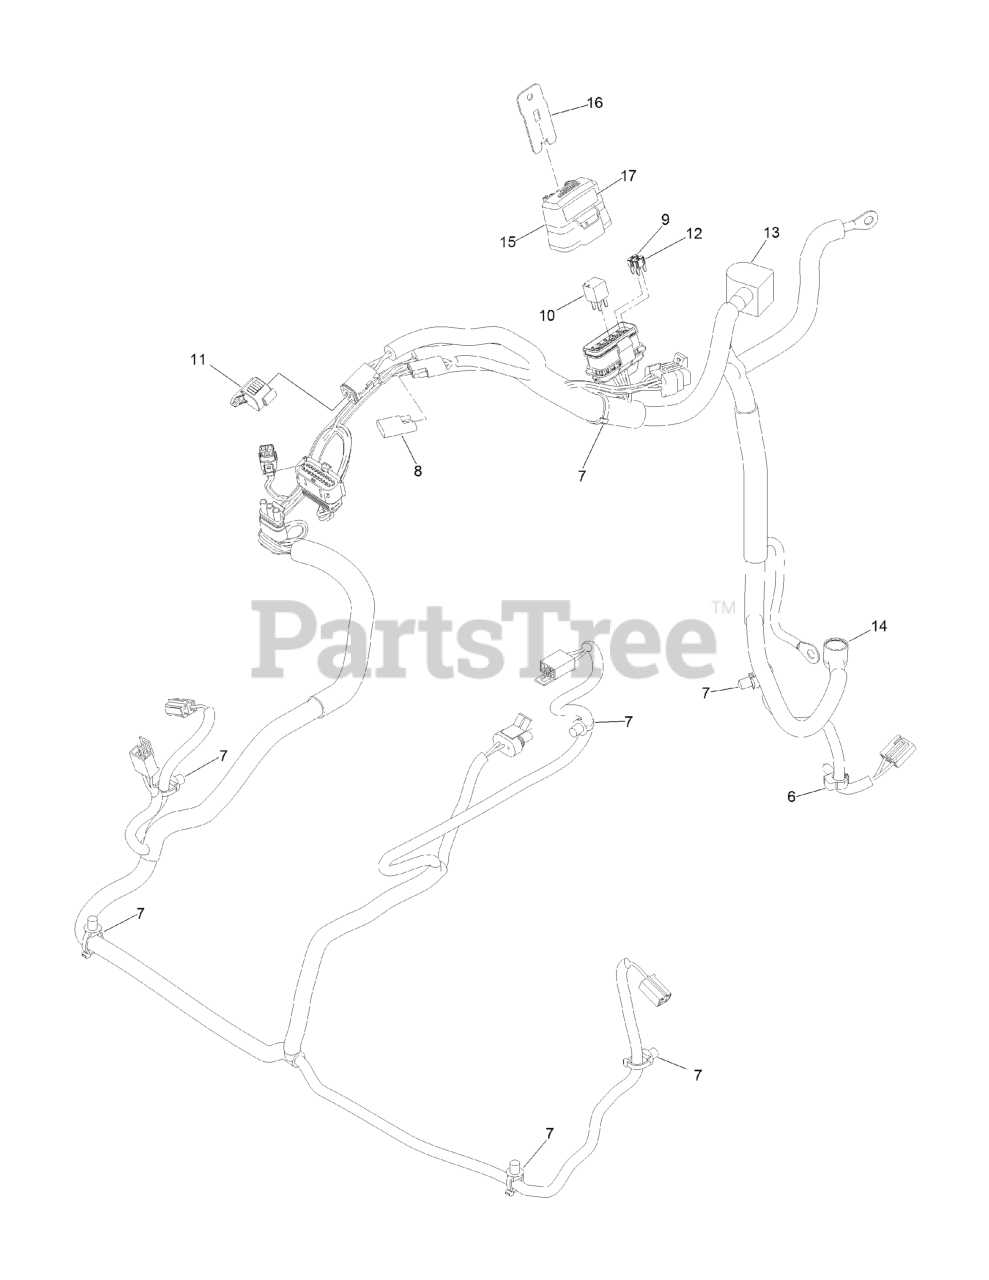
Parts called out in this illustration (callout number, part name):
6	CLIP-HARNESS
7	CLIP-TIE
8	Cap-Plug
9	FUSE-MINI BLADE, 20 AMP
10	RELAY-MICRO
11	CAP-PLUG, 6 WAY
12	FUSE-MINI BLADE, 15 AMP
13	INSULATOR-BATTERY
14	INSULATOR-SOLENOID
15	COVER-BLOCK, FUSE
16	CLIP-MOUNTING
17	DECAL-FUSE
